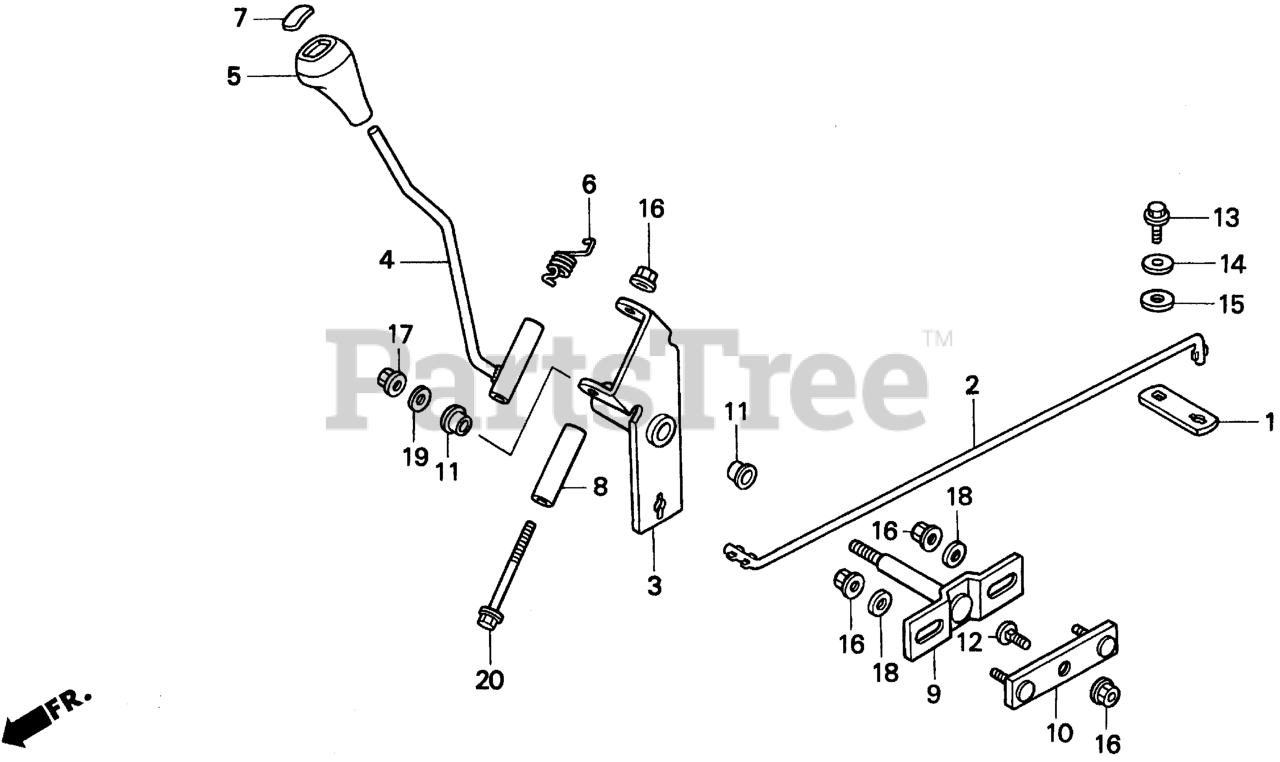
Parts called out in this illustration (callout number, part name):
1	ARM, CHANGE
2	ROD, GEARSHIFT
3	ARM B, CHANGE
4	LEVER, CHANGE
5	GRIP, CHANGE LEVER
6	SPRING, CHANGE LEVER
7	KNOB, CHANGE LEVER GRIP
8	COLLAR, CHANGE LEVER JOINT
9	HOLDER, CHANGE ARM
10	PLATE, ARM MOUNT
11	BUSH (15X17X10)
12	BOLT, SPECIAL (9X15)
13	BOLT, FLANGE (1/4")
14	WASHER (6MM)
15	WASHER, PLAIN (12MM)
16	NUT, FLANGE (8MM)
17	NUT, FLANGE (10MM)
18	WASHER, PLAIN (8MM)
19	WASHER, PLAIN (10MM)
20	BOLT, FLANGE (8X80)
